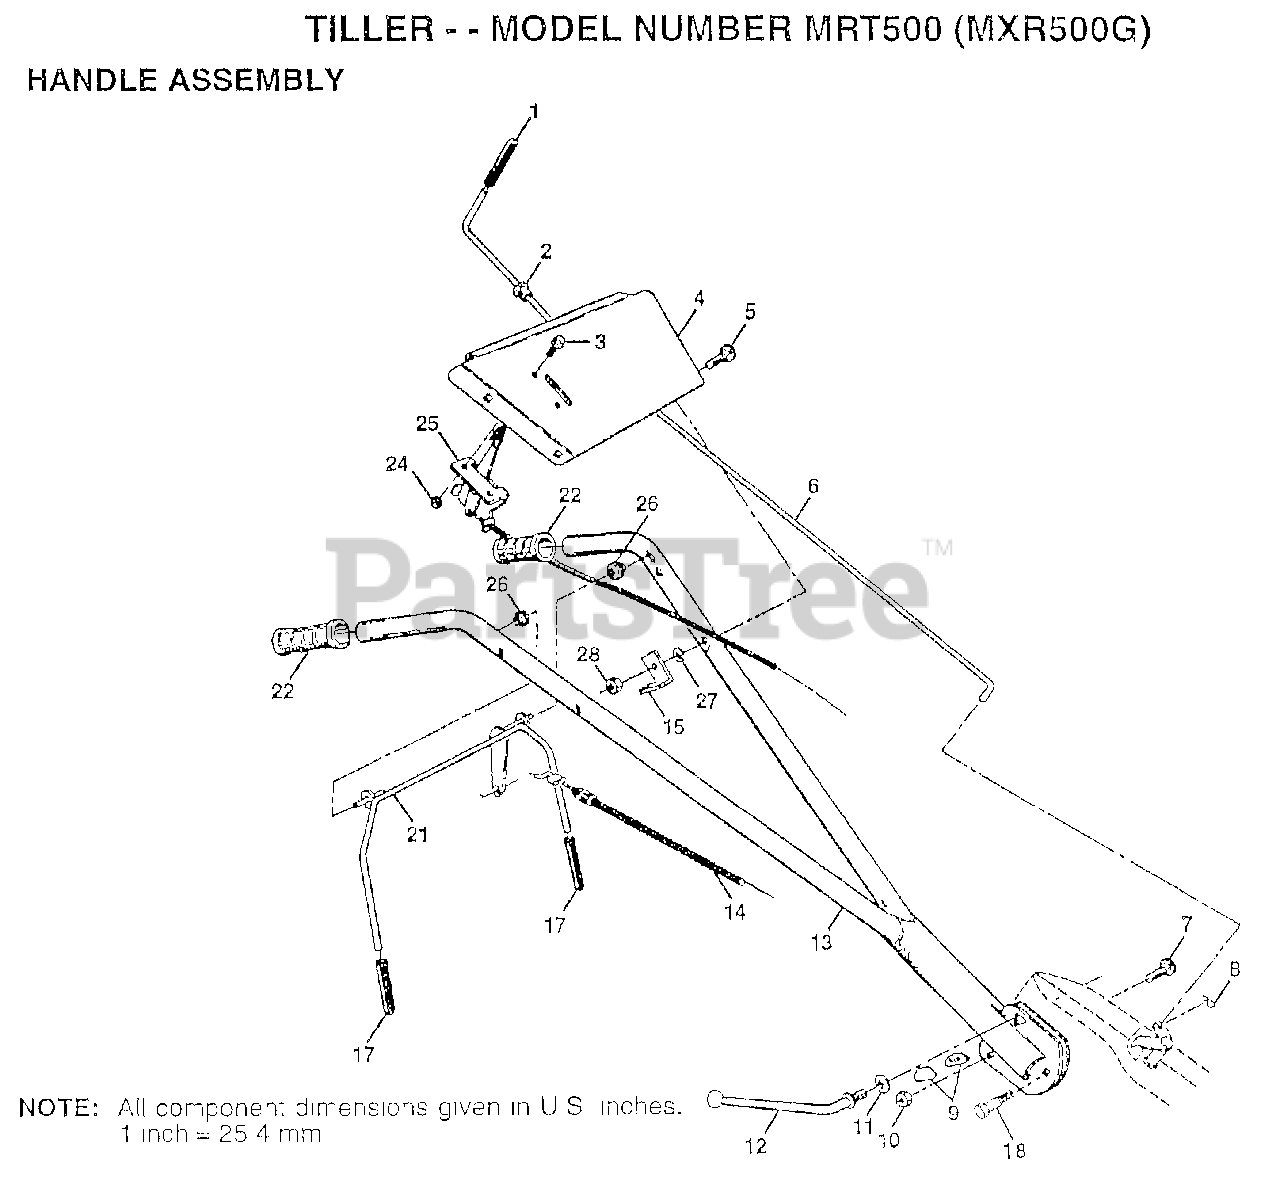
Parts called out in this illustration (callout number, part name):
1	GRIP TI
2	BUSHING
3	SCREW.PNHD.10-24
4	HANDLE BRACKET
5	BOLT CARRIAGE CRT
6	ROD SHIFT CRT
7	BOLT D
8	RETAINER M
9	LOCK CRT
10	LOCKNUT
11	WASHER CRT
12	LEVER LOCK CRT
14	CABLE.CLUTCH.Z-BE
15	BRACKET.CLUTCH.CA
17	GRIP BAR CRT
18	BOLT PIVOT
21	BAR.ASM.CNTRL.VPL
22	"GRIP,HANDLE"
23	NUT
25	"CONT,THROTTLE"
26	GROMMET.HANDLE.V-
27	LOCKWASHER
